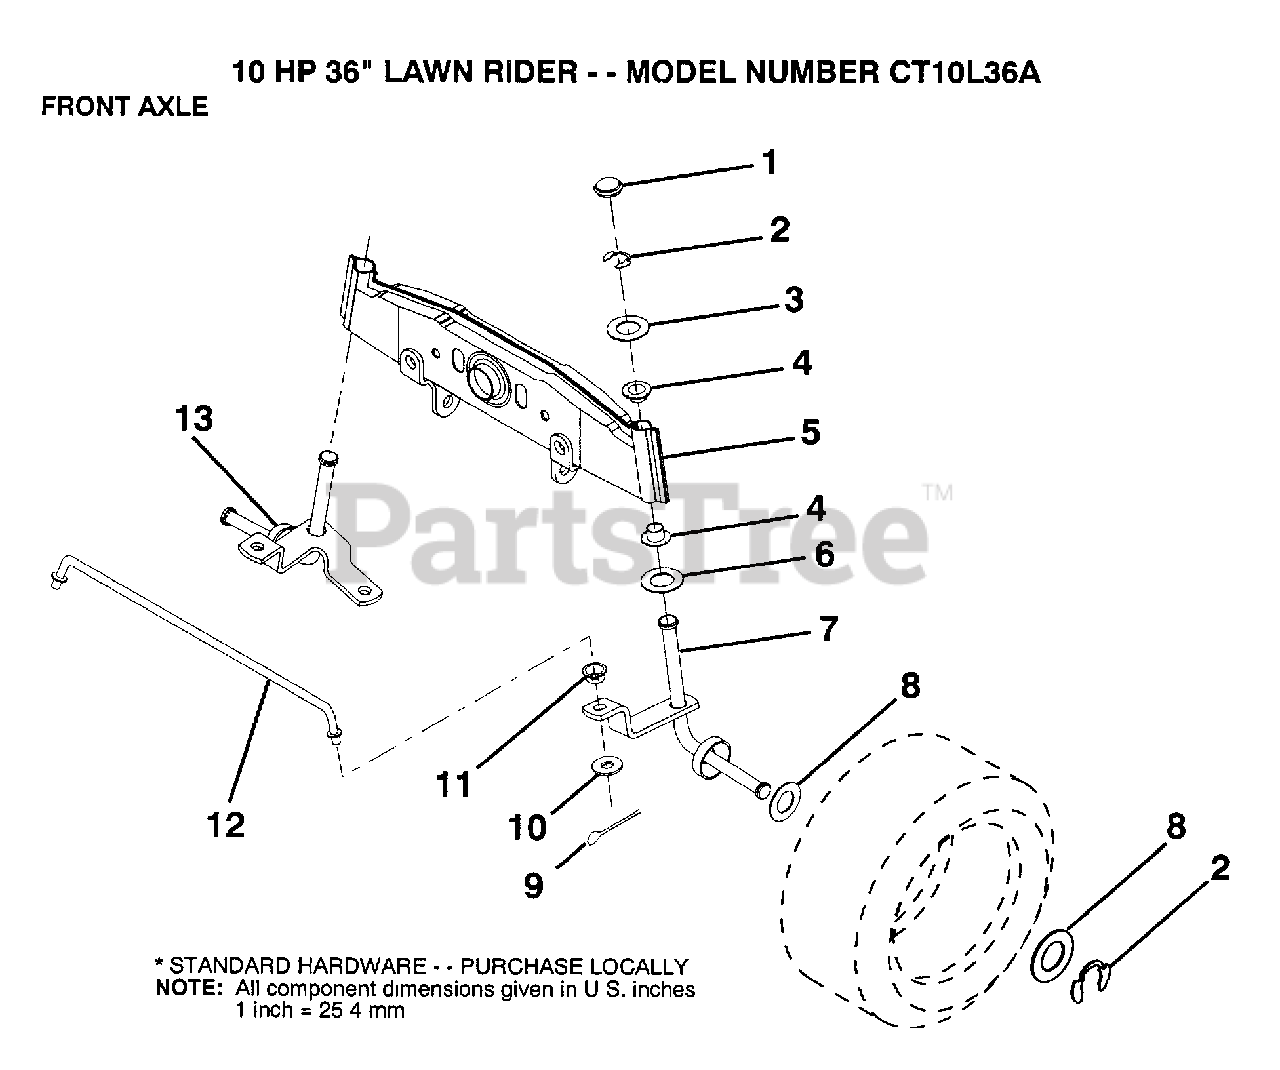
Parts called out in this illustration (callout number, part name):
1	CAP
2	RING
3	WASHER
4	NYLINER
5	AXLE FRONT
6	WASHER .T
7	SPINDLE RH
8	WASHER
9	COTTER PIN
10	WASHER
11	BUSHING.DRAGLINK
12	ROD TIE
13	SPINDLE LH
